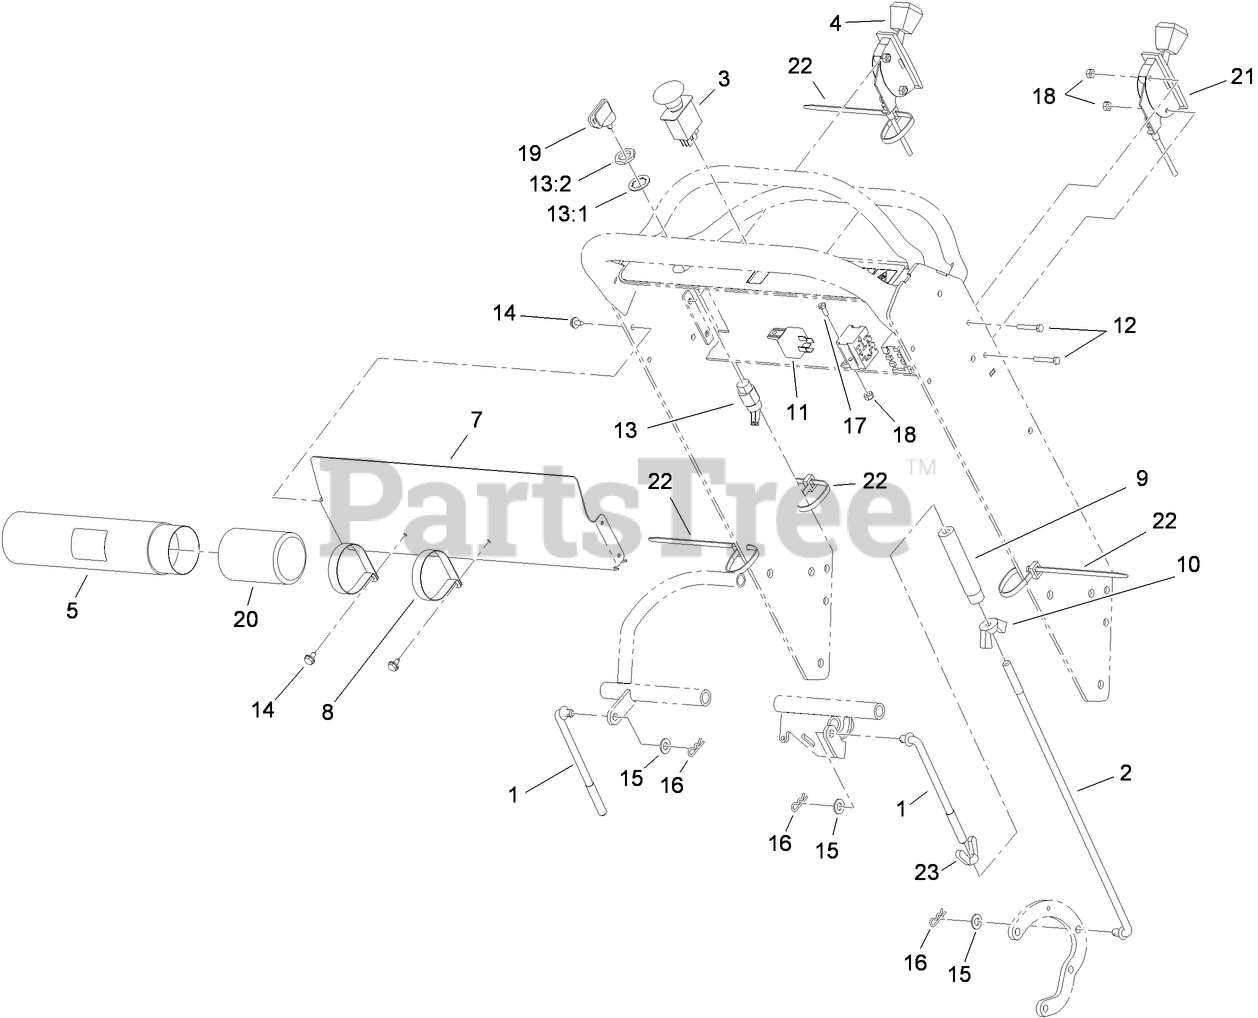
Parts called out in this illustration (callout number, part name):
1	ROD-CONTROL, UPPER
2	ROD-CONTROL, LOWER
3	SWITCH-PTO, ON-ON-(ON)
4	CABLE-THROTTLE
5	TUBE-MANUAL
7	COVER-PANEL, CONTROL
8	CLAMP-R
9	TURNBUCKLE
10	NUT-WING
12	SCREW-HH
13	SWITCH-ON / OFF
13:1	NUT-HH
13:2	WASHER-TOOTH, INTERNAL
14	SCREW-HWHTF
15	WASHER-PLAIN
16	PIN-COTTER
17	SCREW-SHH
18	NUT-LOCK, NI
19	KEY-IGNITION
20	CAP-HOUSING
21	CABLE-CHOKE
22	TIE-CABLE
23	NUT-WING, LH
